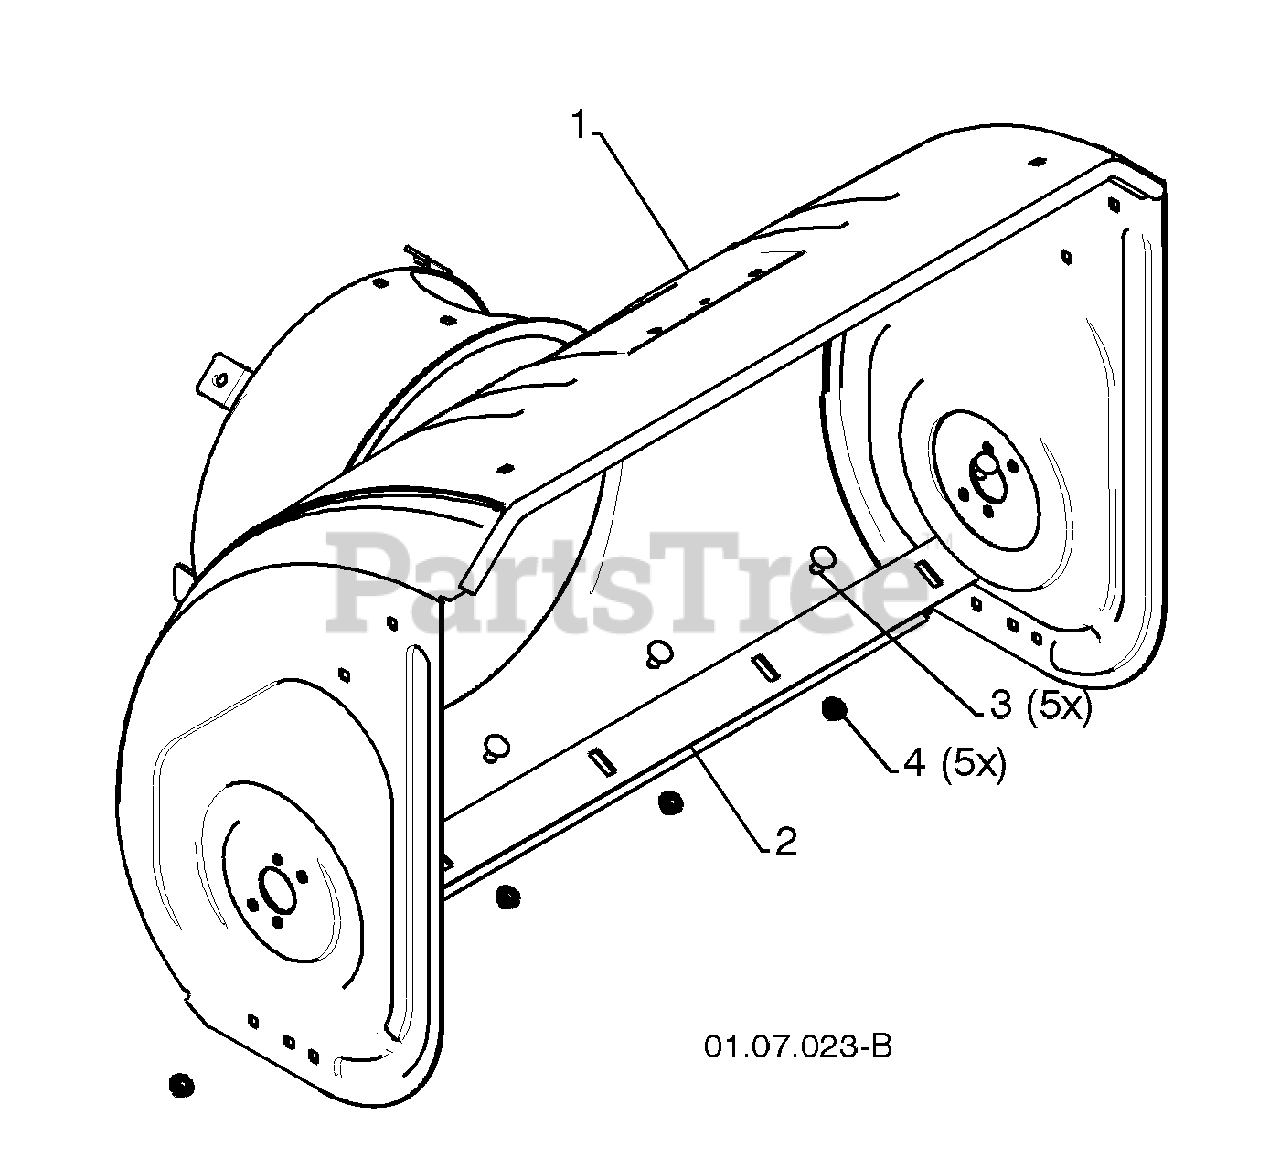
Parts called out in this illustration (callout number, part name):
1	AUGER HOUSING
2	SCRAPPER BAR
3	CARRIAGE BOLT 5/16-18 X .625
4	NUT 5/16-18
